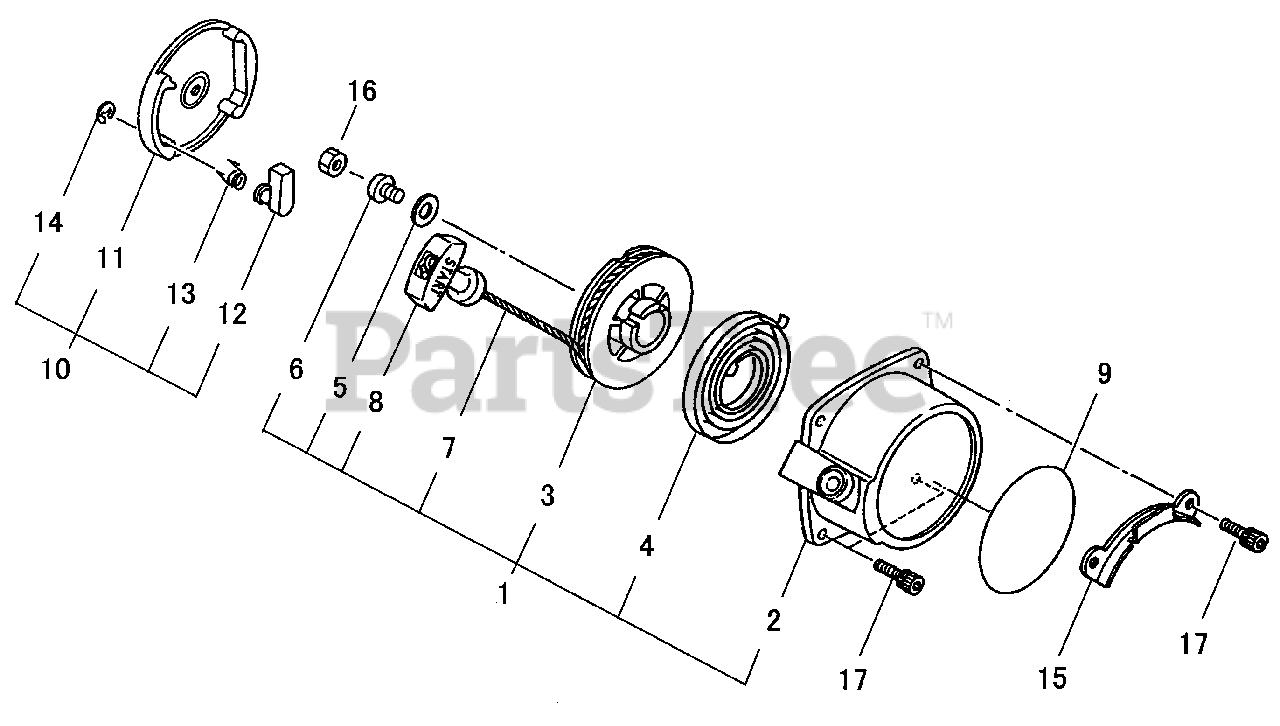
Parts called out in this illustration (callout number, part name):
1	STARTER ASSY, RECOIL
2	CASE, STARTER
3	REEL, ROPE
4	SPRING, RECOIL
5	WASHER 5
6	SCREW 5
7	ROPE, STARTER
8	GRIP, STARTER
9	LABEL, RECOIL STARTER
10	PULLEY ASSY, STARTER
11	PULLEY, STARTER
12	RATCHET
13	SPRING, RETURN
14	E-RING
15	BRACKET
16	NUT
17	BOLT, ADHESIVE M4×16
